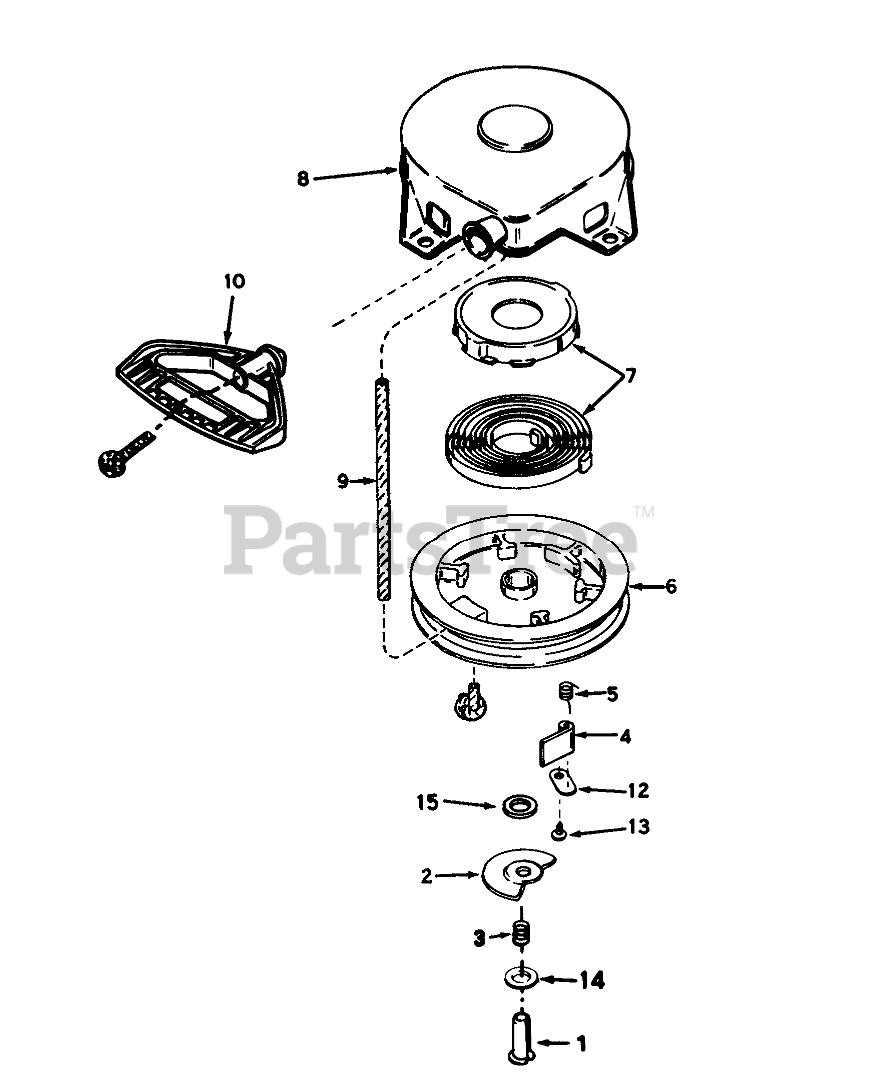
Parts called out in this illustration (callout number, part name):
1	Pin-Spring (Incl. Ref. #15)
3	Brake Spring
4	Dog-Starter
5	Spring-Dog
7	Spring & Keeper Assy
8	Housing-Starter
9	Rope-Starter
10	Handle-Starter, Mitten Grip
12	Retainer-Dog
